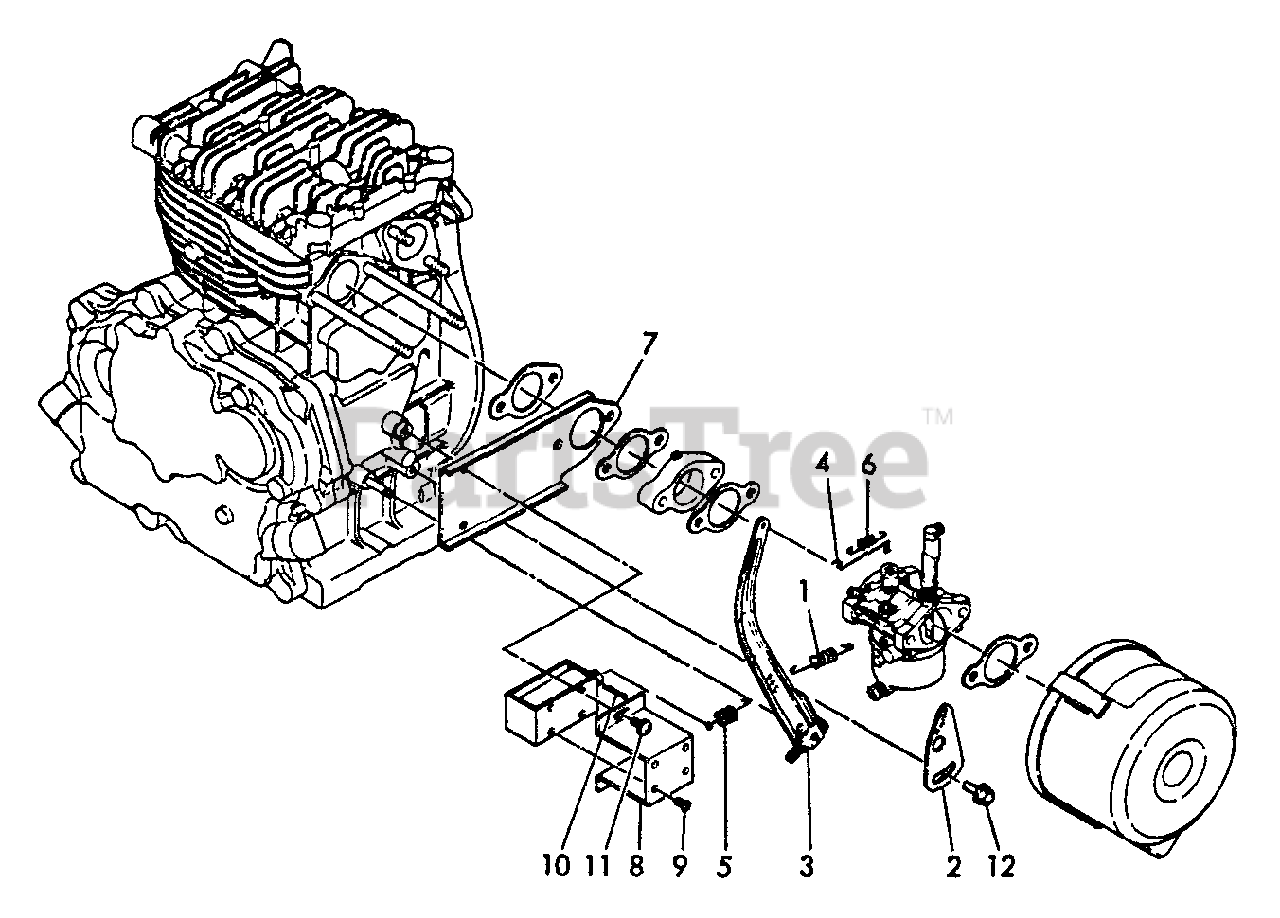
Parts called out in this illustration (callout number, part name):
1	SPRING, REGULATOR
2	HANDLE, REGULATOR
3	LEVER, GOVERNOR
4	LINK, THROTTLE
5	SPRING
6	SPRING, TENSION
7	MOUNT, SOLENOID
8	HOLDER, SOLENOID
9	SCREW - 3×4
10	PIN - 2.5×20 -- COTTER
11	SCREW - 5×10
12	BOLT - 6×8 -- PLATED
